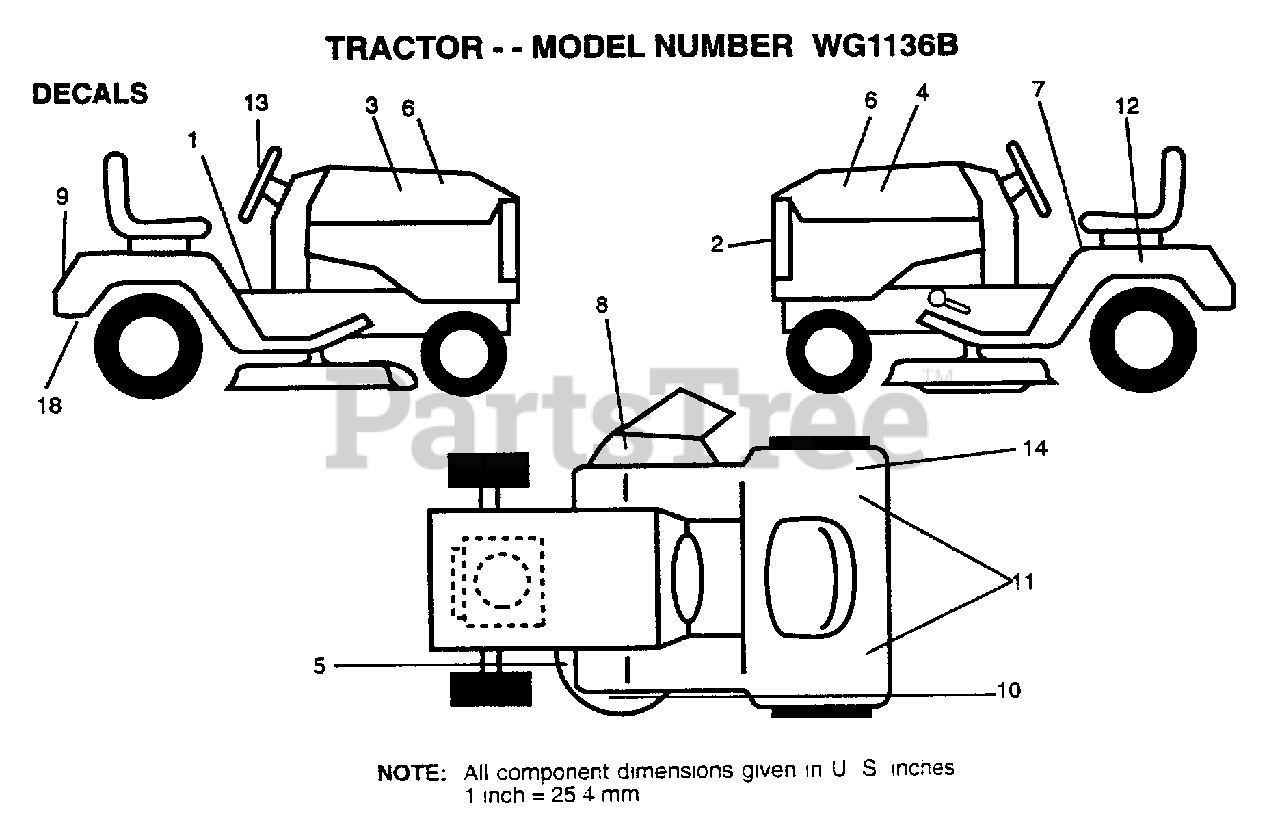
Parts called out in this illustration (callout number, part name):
1	DECAL.OP.INST.SYM
2	"DECAL,LIGHT BOX"
3	DECAL STRIP HD RH
4	DECAL STRIP HD LH
5	DECAL.V.BELT
6	DECAL.PNL.SIDE.
7	DECAL.READ.O.MANU
8	DECAL.DANGER.CUTF
9	DECAL.FENDER
10	DECAL.MOWER
11	DECAL.FEND.QUICKS
12	DECAL.BATRY.3-3908
13	DECAL.WHL.STRG.
18	DECAL.EURO.ST.CE.
